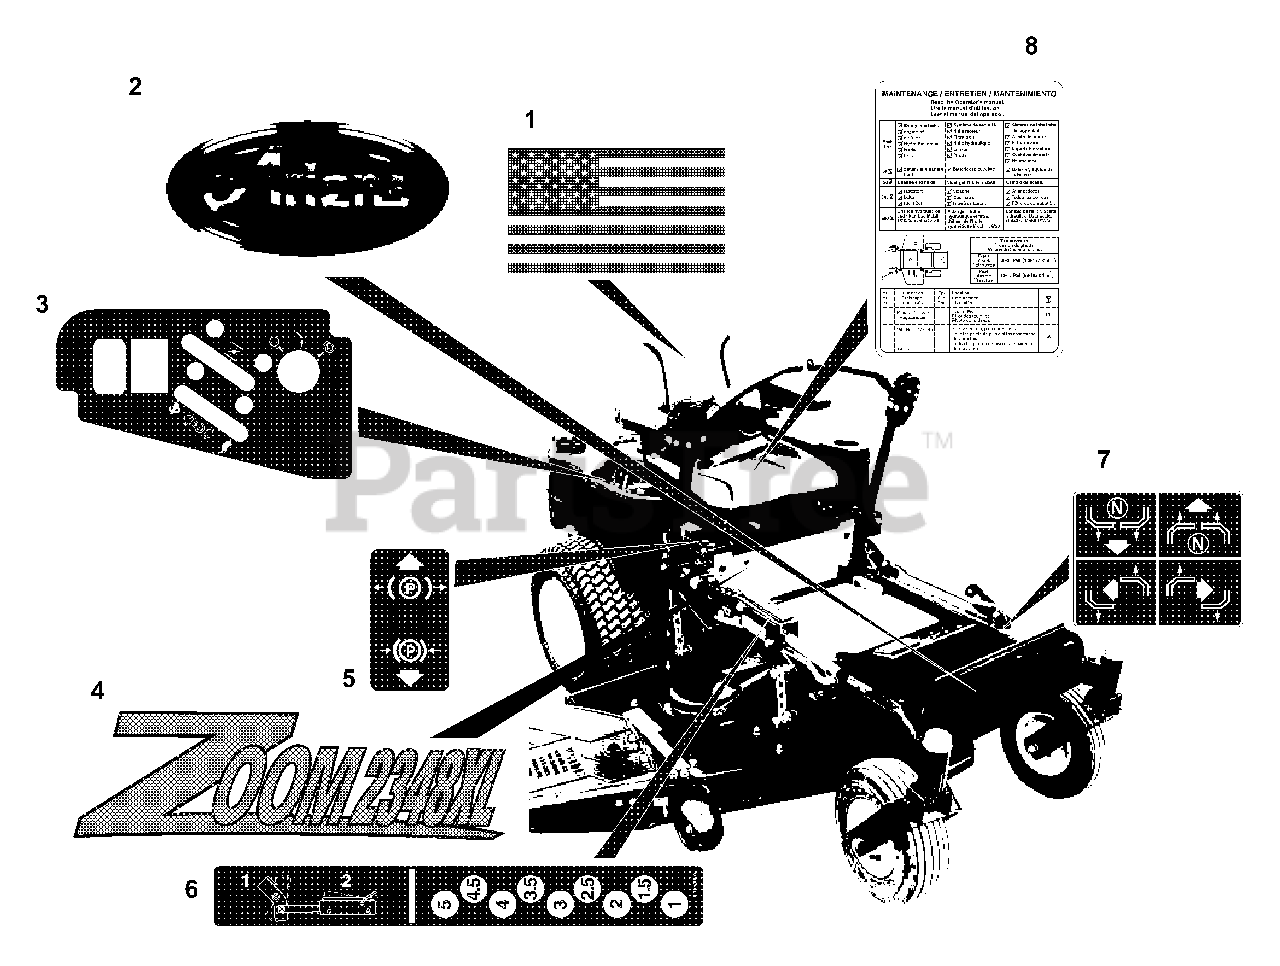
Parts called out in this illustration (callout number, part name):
1	DECAL, AMERICAN FLAG
2	DECAL, ARIENS JEWEL
3	DECAL, CONTROL PANEL COMPACT Z
4	DECAL, ZOOM 2044XL
5	DECAL, PARKING BRAKE LEVER
6	DECAL, HEIGHT OF CUT COMPACT-Z
7	DECAL, INSTRUCTIONAL-STEERING
8	DECAL, MAINTENANCE INSTRUCTION
